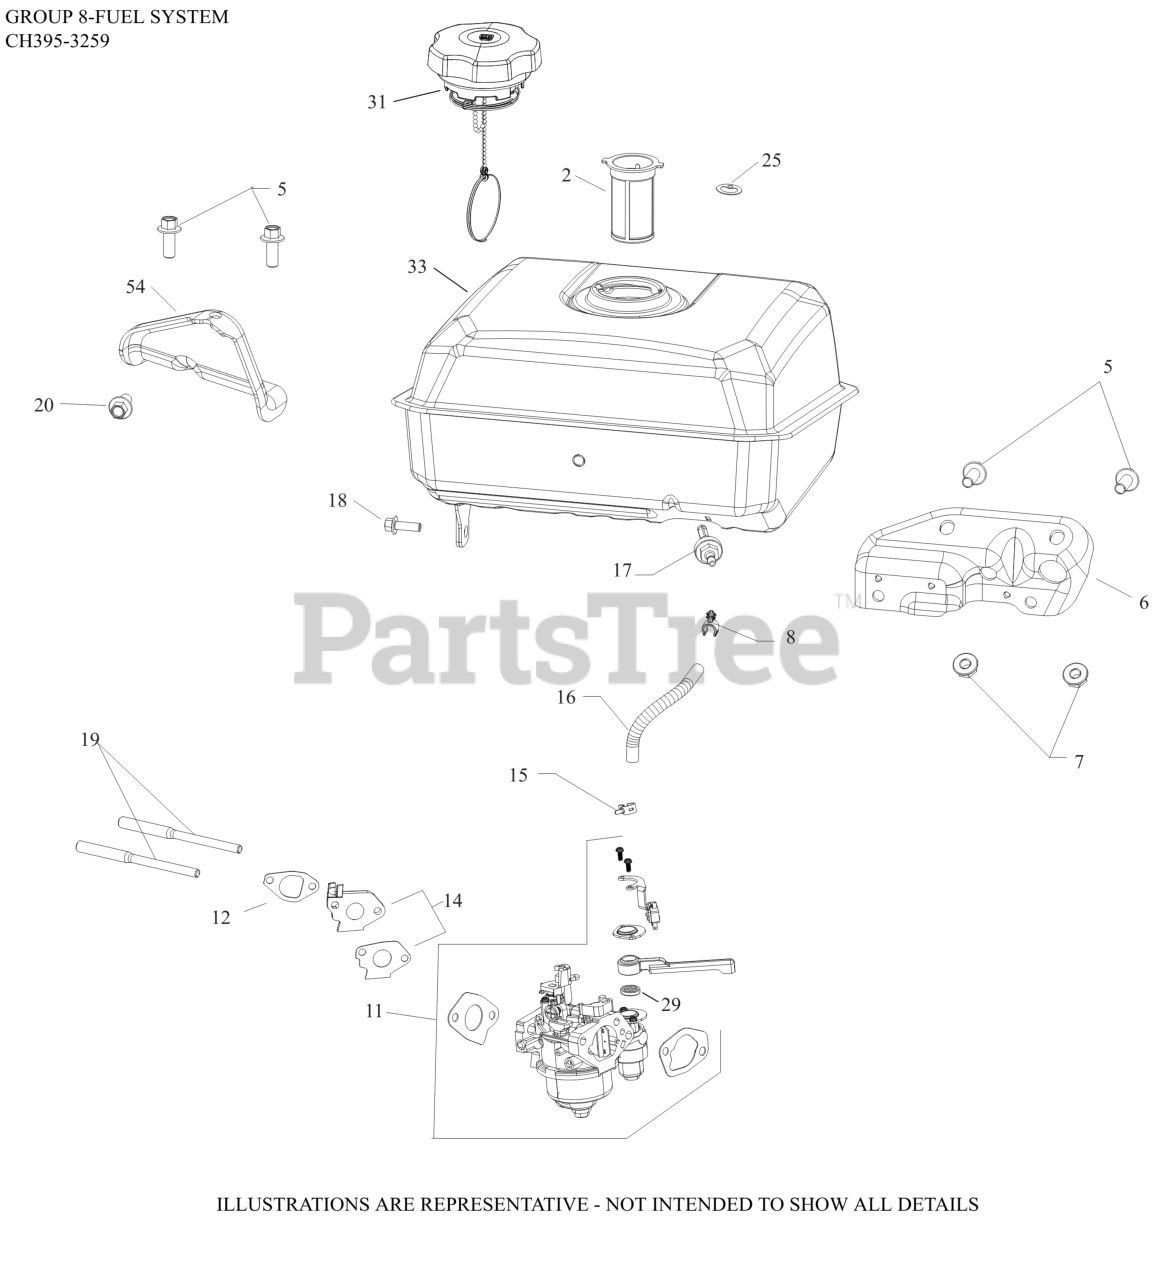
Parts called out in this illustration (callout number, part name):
2	FILTER, FUEL TANK
5	SCREW, M8 X 20
6	BRACKET, FUEL SUPPORT ASSEMBLY
7	NUT, FLG M8X1.25
8	CLIP, FUEL HOSE
11	KIT, CARBURETOR COMPLETE
12	KIT, INTAKE GASKETS
14	INSULATOR AND GASKET KIT
15	CLAMP, FUEL LINE
16	LINE, FUEL (10"-CUT TO LENGTH)
17	FITTING, FUEL ASSY
18	SCREW, M6 X18
19	STUD, CARBURETOR
20	SCREW, FLG 8X1.25X16
25	KIT, FUEL SCREEN
29	SEAL, INLET VALVE
31	CAP, FUEL ASSEMBLY
33	TANK, FUEL
54	BRACKET, FUEL SUPPORT
NI	KIT, HIGH ALTITUDE (4,000-8,000 FT)
NI	KIT, HIGH ALTITUDE (ABOVE 8,000 FT.)
NI	KIT, CARBURETOR REPAIR
